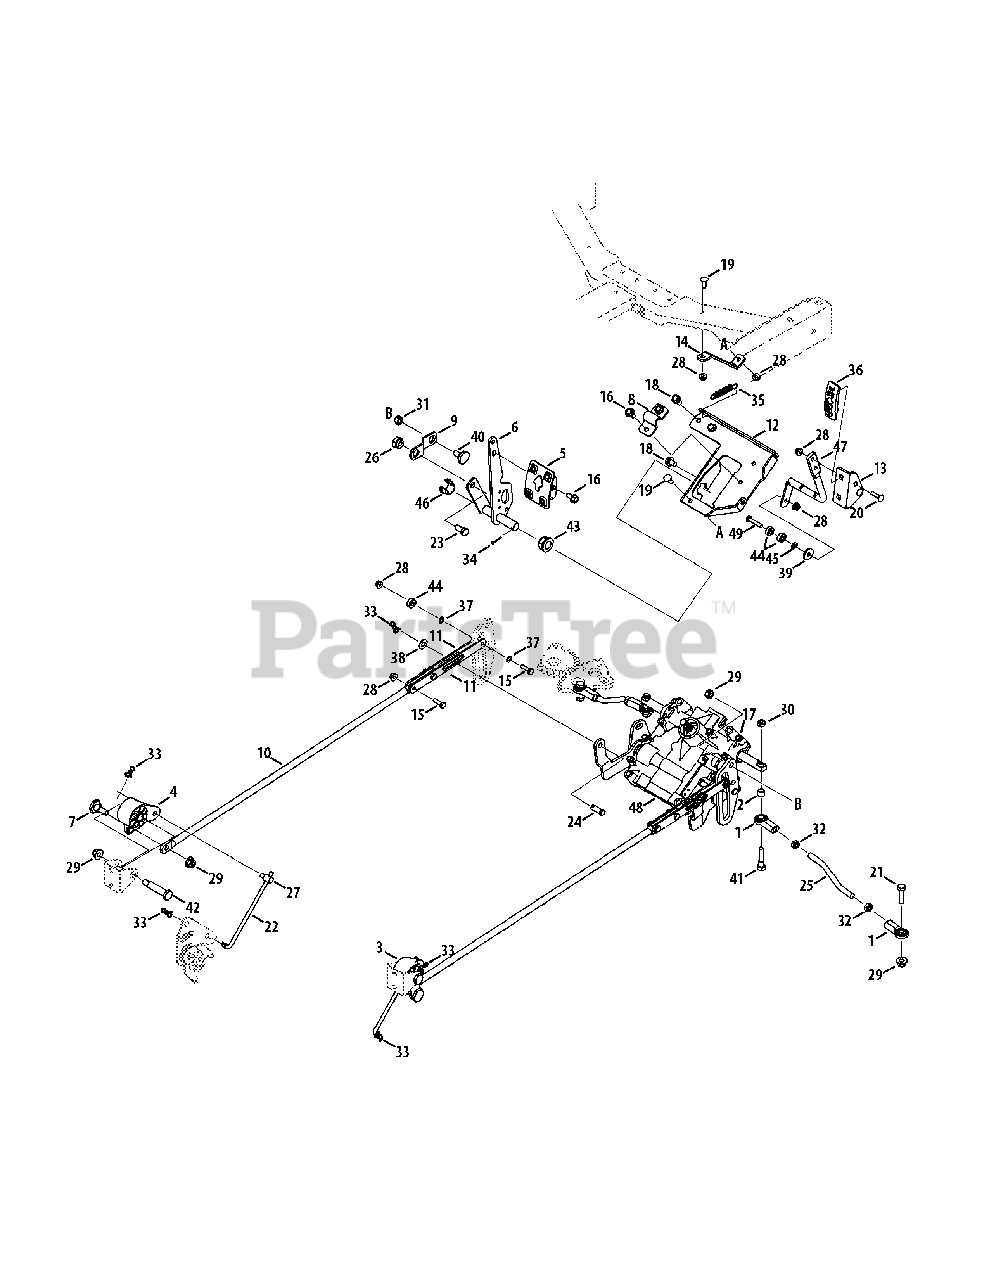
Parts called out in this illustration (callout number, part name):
1	Female Ball Joint, 3/8-24
2	Spacer, 344 x .500 x .375
3	Right Pivot Arm
4	Left Pivot Arm
6	Forward Bracket Assembly
7	Scr., Sldr., .500 x .434
8	Reverse Bearing Bracket
9	Control Bracket
10	Hydro Link Rod
11	Steering Link Plate
16	Hex Washer Screw, 5/16-18 x .750
17	Hex Washer Screw, 1/4-20 x .500
18	Hex Washer Screw, 5/16-18 x .625
19	Carriage Screw, 1/4-20 x .75
20	Carriage Screw, 1/4-20 x 1.00
21	Hex Screw, 3/8-16 x 1.25
22	Hydro Control Rod
23	Hex Screw, 3/8-16 x .750
24	Clevis Pin, .375 x .969
25	Rod, 3/8 x 5.0
26	Neutral Adjustment Hub
27	Adjustment Ferrule, 1/4-28 x 1.000
28	Flange Lock Nut, 1/4-20
29	Flange Lock Nut, 3/8-16
30	Hex Lock Nut, 5/16-24
31	Hex Lock Nut, 3/8-16
32	Jam Nut, 3/8-24
33	Bow-Tie Cotter Pin, 72
34	Cotter Pin, 3/32 x .750
35	Extension Spring, .429 x 2.515
36	Reverse Foot Pad
37	Flat Washer, .281 x .50 x .04
38	Thrust Washer, .375 x .812 x .060
39	Wash., Fl., .265 x .938 x .120
40	Shoulder Screw, .625 x .217
41	Shoulder Screw, 375 x .48
42	Shoulder Screw, .500 x 1.825
43	Hex Flange Bearing
44	Ball Bearing, .25 x .6875 x .25
45	Wash., Fl., .281 x .500 x .063
46	Hex Flange Bearing, .628
47	Reverse Pedal Assembly
48	Steering Assembly
49	Screw, 1/4-20 x 1.25
